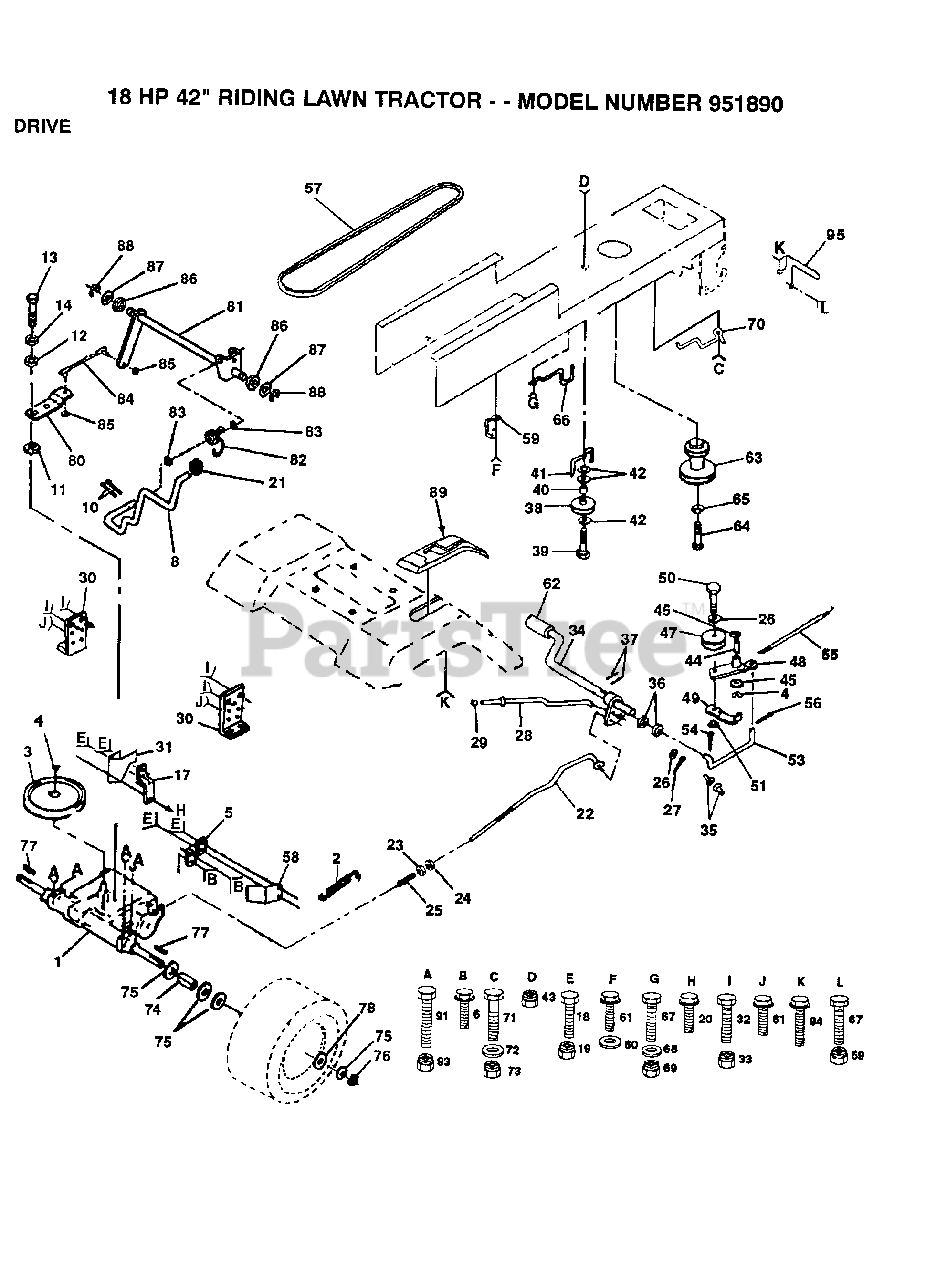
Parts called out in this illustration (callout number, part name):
3	"PULLEY,TRANSAXLE"
5	STRAP TORQUE
6	SCREW
10	PIN COTTER 1/8
11	WASH-SHFT PLT LT
12	WASHER
14	LOCKWASHER
17	STRAP TORQUE
20	SCREW
21	KNOB T (1/2-HOLE)
22	BRAKE ROD
23	NUT
24	NUT
25	SPRING ROD LT
26	WASHER
27	COTTER PIN
28	BRAKE PARK ROD
29	PLUNGER CAP T
30	TRANSAXLE MTG BKT
31	"KEEPER,BELT LH"
32	BOLT
35	NYLON BEARING
36	WASHER LT
38	PULLEY.IDLER.FLAT
39	BOLT
40	SPACER T
41	BELT KEEPER LT
42	WASHER
44	"LY, BEARING"
45	WASHER LT
46	KLIP RING
48	ARM IDLER
49	RETAIN BELT
52	WASHER HYT
53	"LINK, CLUTCH T"
54	COTTER PIN
55	"SPRING, RETURN LT"
56	COTTER PIN
57	BELT-V
58	"KEEPER,BELT RH"
60	WASHER
61	SCREW
62	PEDAL COVER T
64	BOLT
65	LOCKWASHER
66	KEEPER.BELT.ENG.L
67	BOLT
68	WASHER
70	KEEPER BELT ENG
71	BOLT
72	WASHER
74	SPACER LT
75	WASHER
76	E-RING LT
77	SQUARE KEY
78	WASHER
80	ARM SHIFT TRANS
82	"SPRING,TORSION"
83	WASHER
84	TIE ROD
85	NUT 1/4-28
86	"BUSH,PIVOT T"
87	"WSHER,SHIM"
88	RING T
91	BOLT
94	SCREW GTV
95	MUFFLER GUARD
